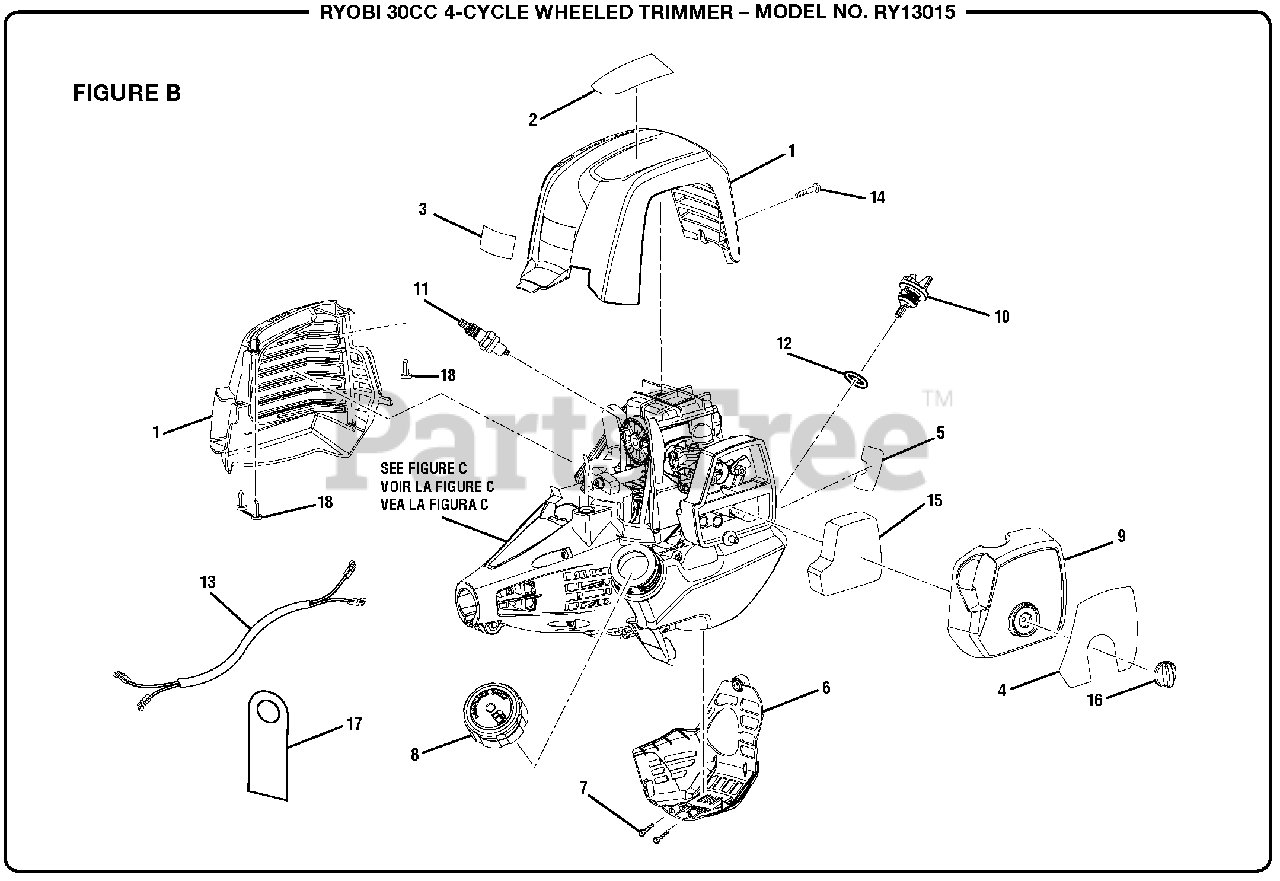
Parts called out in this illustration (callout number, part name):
1	Top Cover Assembly (Inc. Key No. 18)
2	Label
3	Logo Label
4	Starting Label
5	Hot Surface Label
6	Bottom Cover
7	Screw (M6-19 x 1/2 in.)
8	Fuel Cap Assembly
9	AIr Box Cover
10	Oil Cap/Dipstick
11	Spark Plug (Champion RY4C)
12	O-Ring
13	Wiring Harness
14	Screw (M4 x 20 mm)
15	Air Filter
16	Air Cover Knob
17	Hangtag
18	Screw (M4 x 12 mm)
